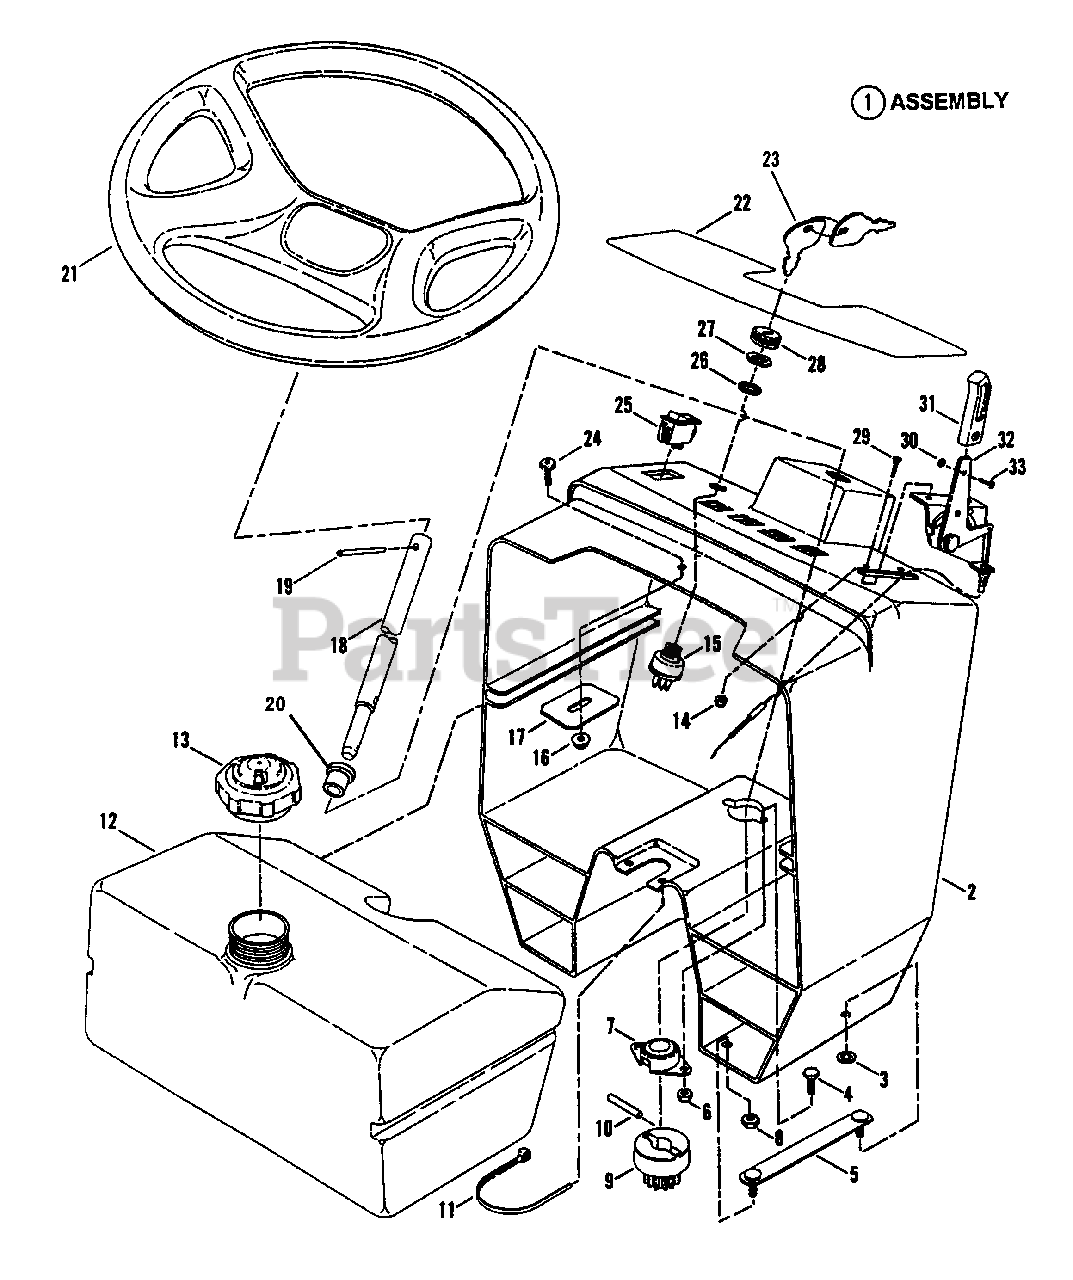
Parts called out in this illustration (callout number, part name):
1	ASSEMBLY, Console
2	CONSOLE
3	RETAINER
4	SCREW, 1/4-20 x 3/4" Hex Head Cap, Grade 5
5	ASSEMBLY, Strap-Clinch Stud
6	NUT, 1/4-20 Hex Nyloc
7	ASSEMBLY, Flange Bearing
8	NUT, 5/16-18 Hex Center Lock, Grade 5
9	GEAR, Pinion, Steering Shaft
10	PIN, Dowel, 1/4 x 1-1/4"
11	TIE, Wire
12	ASSEMBLY, Fuel Tank
13	CAP, Fuel Tank
14	NUT, #10-24 Hex Nyloc
15	KEYSWITCH
16	NUT, 5/16-18 Hex Flange Center Lock
17	BRACKET, Hood Latch Catch
18	SHAFT, Steering
19	ROLL-PIN
20	BUSHING
21	STEERING WHEEL
22	DECAL, Console
23	KEY, Pair
24	SCREW, 5/16-18 x 5/8" Truss Head, Torx
25	SWITCH, Lights
27	NUT, 5/8-32 Hex
28	BEZEL
29	SCREW, #10-24 x 5/8" Machine
30	NUT, #8-32 Hex
31	HANDLE, Throttle Control
32	CONTROL, Throttle
33	SCREW, #8-32 x 3/8" Cross-Recessed, Machine
